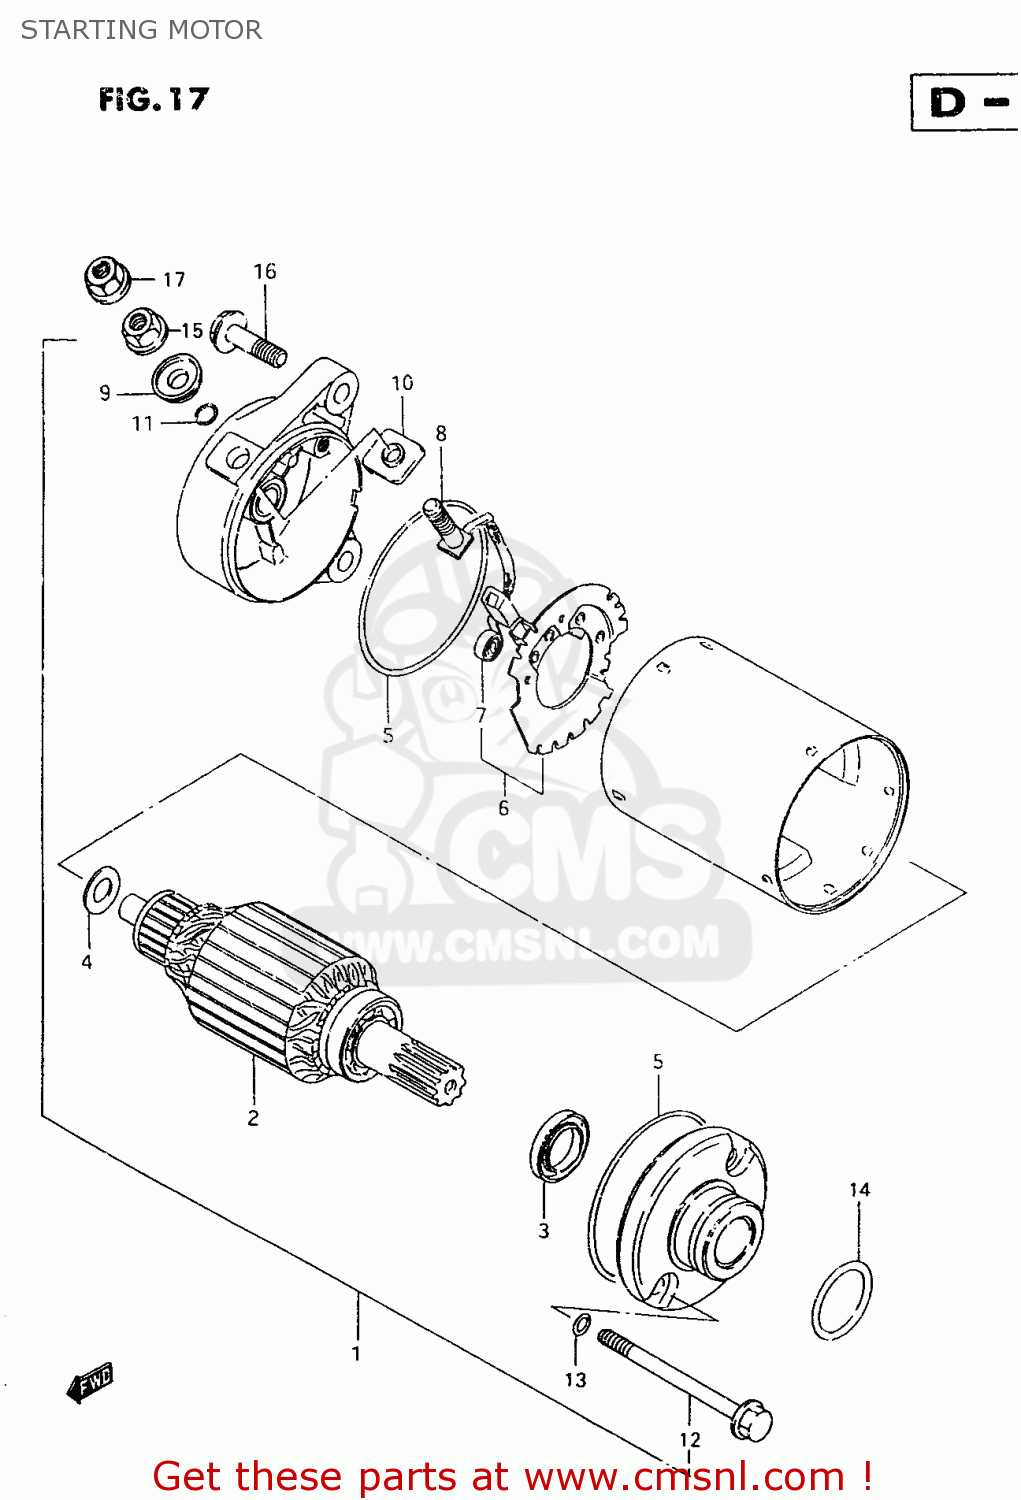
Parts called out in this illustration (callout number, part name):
1	MOTOR ASSY,STARTING
2	ARMATURE
3	SEAL,OIL
4	SHIM SET,STARTING MOTOR
5	O RING
6	HOLDER,BRUSH
7	SPRING
8	BRUSH SUB ASSY,STARTING MOTOR
9	BUSHING
10	BUSH,B
11	O RING
12	BOLT
13	O RING
14	O RING(D:3,ID:24.5)
15	NUT
16	BOLT
17	NUT
